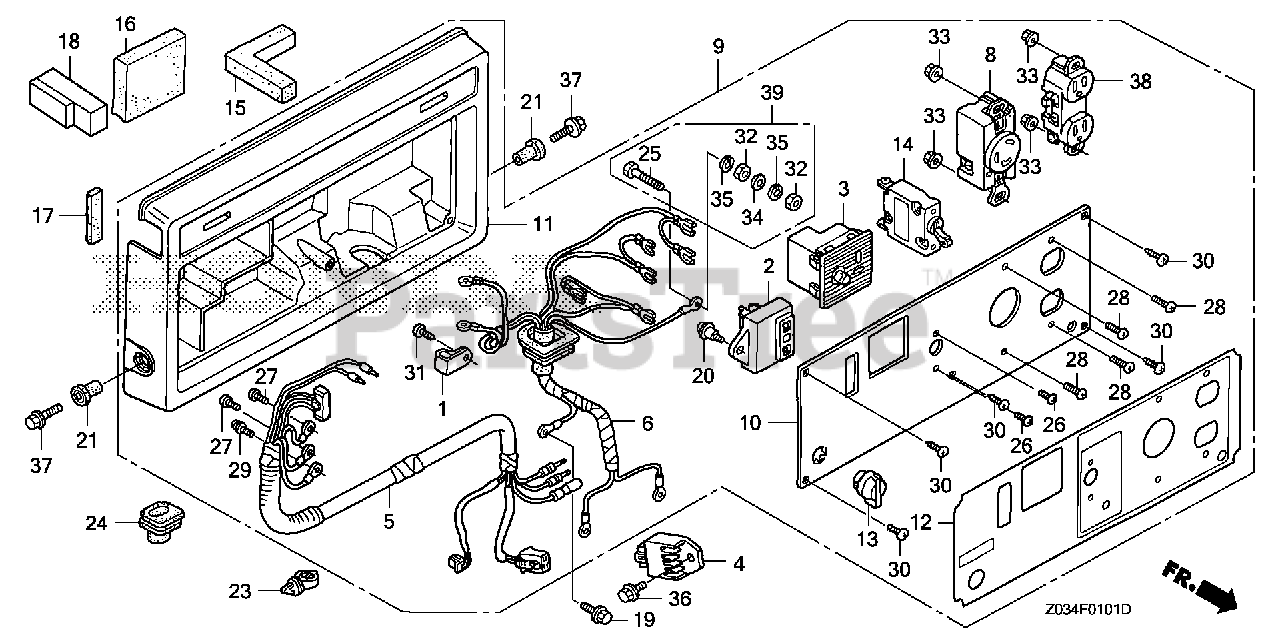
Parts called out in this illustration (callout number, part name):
1	CLAMP C, CABLE
2	IGNITION UNIT
3	RECEPTACLE, D.C.
4	RECTIFIER ASSY.
5	WIRE HARNESS ASSY., MAIN
6	SUB-WIRE HARNESS ASSY.
8	RECEPTACLE (20A/125V)
9	BOX ASSY., CONTROL
10	PANEL, CONTROL
11	CASE, CONTROL (C1)
12	MARK, CONTROL PANEL
13	SWITCH ASSY., ENGINE STOP (RED)
14	BREAKER, CIRCUIT (20A)
15	INSULATOR (A)
16	INSULATOR (B)
17	INSULATOR (C)
18	INSULATOR (D)
19	BOLT, FLANGE (6X12) (CT200)
20	SCREW, PAN (5X13)
21	NUT, WELL (6MM)
23	CLIP, HARNESS
24	GROMMET, WIRE HARNESS
25	BOLT, HEX. (6X22)
26	SCREW, PAN (3X5)
27	SCREW, PAN (3X8)
28	SCREW, PAN (4X10)
29	SCREW-WASHER (4X8)
30	SCREW, TAPPING (5X10)
31	SCREW, TAPPING (5X12)
32	NUT, HEX. (6MM)
33	NUT, FLANGE (4MM)
34	WASHER, PLAIN (6MM)
35	WASHER, SPRING (6MM)
36	BOLT, FLANGE (6X12)
37	BOLT, FLANGE (6X20)
38	RECEPTACLE (20A/125V)
39	TERMINAL SET, GROUND
